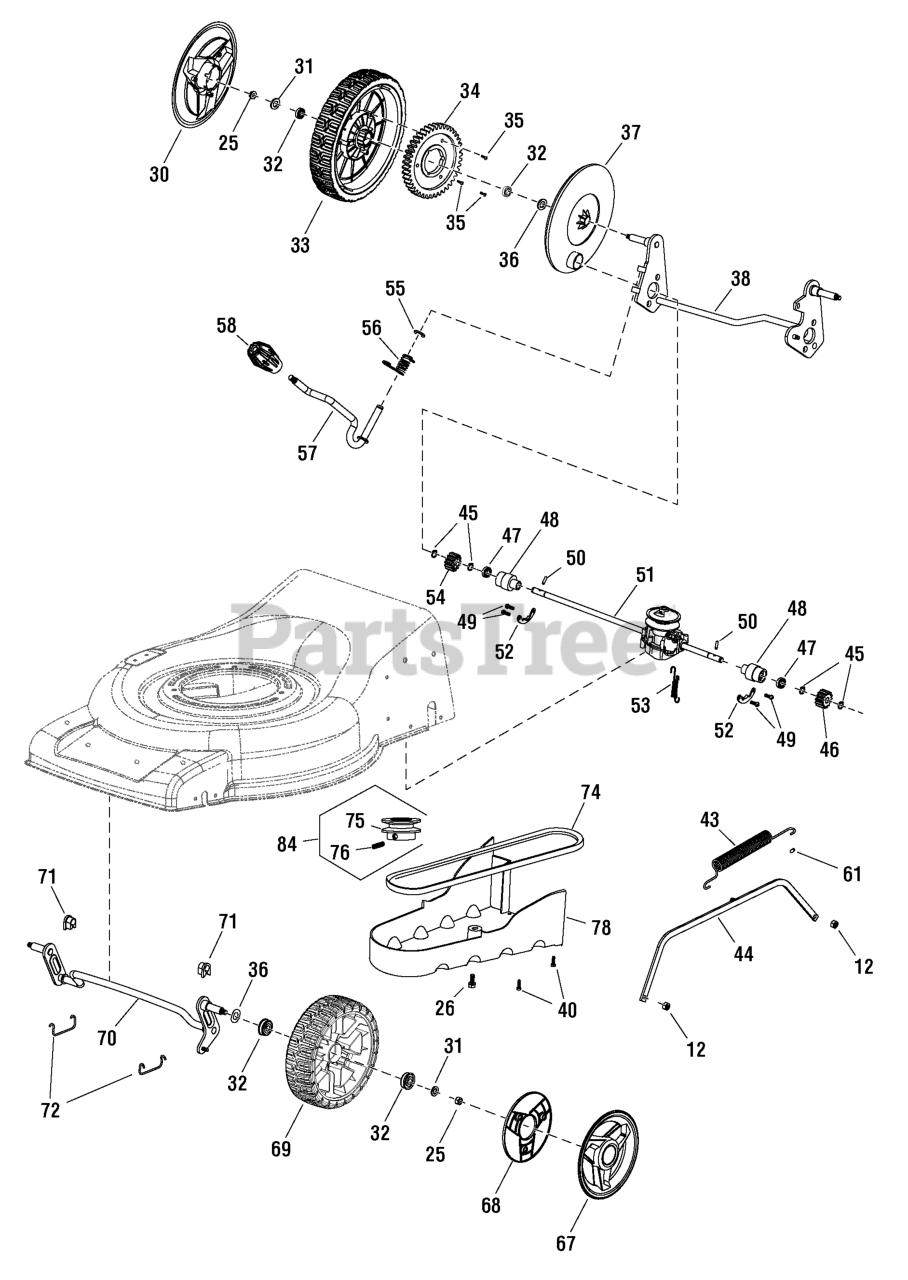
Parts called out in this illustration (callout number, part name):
12	NUT, M6
25	NUT, Hex, M8
26	BOLT, Hex Flange, M8 x 16
30	HUBCAP, Rear
31	WASHER, Plain, 8
32	BEARING
33	WHEEL, Rear
35	SCREW, ST 4.8 x 16
36	WASHER, Wave
37	DUST COVER, Rear
38	AXLE, Rear
40	SCREW, With Washer, ST4.8 x 13
43	SPRING, Connecting Rod
44	CONNECTING ROD
45	WASHER, Ring, 12
46	DRIVE GEAR, Left
47	BEARING
48	BUSHING
49	SCREW, M6 x 12
51	GEAR BOX ASSEMBLY
52	RETAINER, Axle
53	SPRING, Tension
54	DRIVE GEAR, Right
55	WASHER, Split, 8
56	SPRING, Height Adjust
57	LEVER, Height Adjust
58	KNOB, Height Adjust
61	CAP, Spring
67	HUBCAP, Front
68	DUST COVER
69	WHEEL, Front
70	AXLE, Front
71	BUSHING
72	CLIP, Axle
74	V-BELT
75	PULLEY, Belt
76	SCREW, Set, M6 x 10
78	COVER, Belt
84	KIT, Belt Pulley
